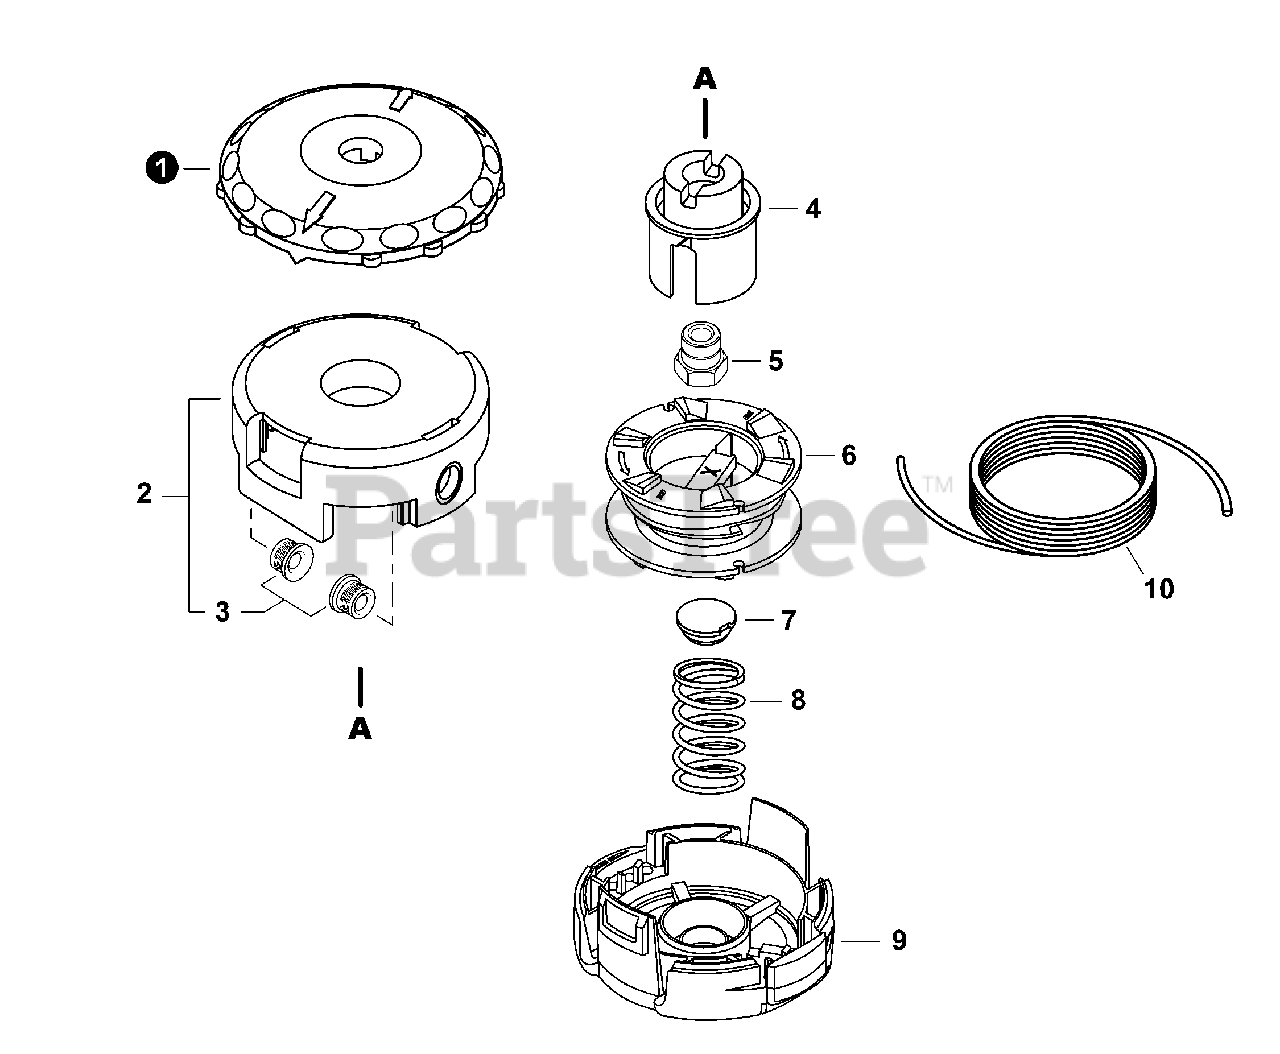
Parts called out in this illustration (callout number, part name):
2	HOUSING ASSY, SPOOL
4	HUB (LH) BLACK
5	BUSHING M10×1.25 LH GOLD
7	CAP, SPRING
8	SPRING, GOLD
9	COVER, SPOOL
10	LINE, NYLON - 40' SILENTWIST GREEN
